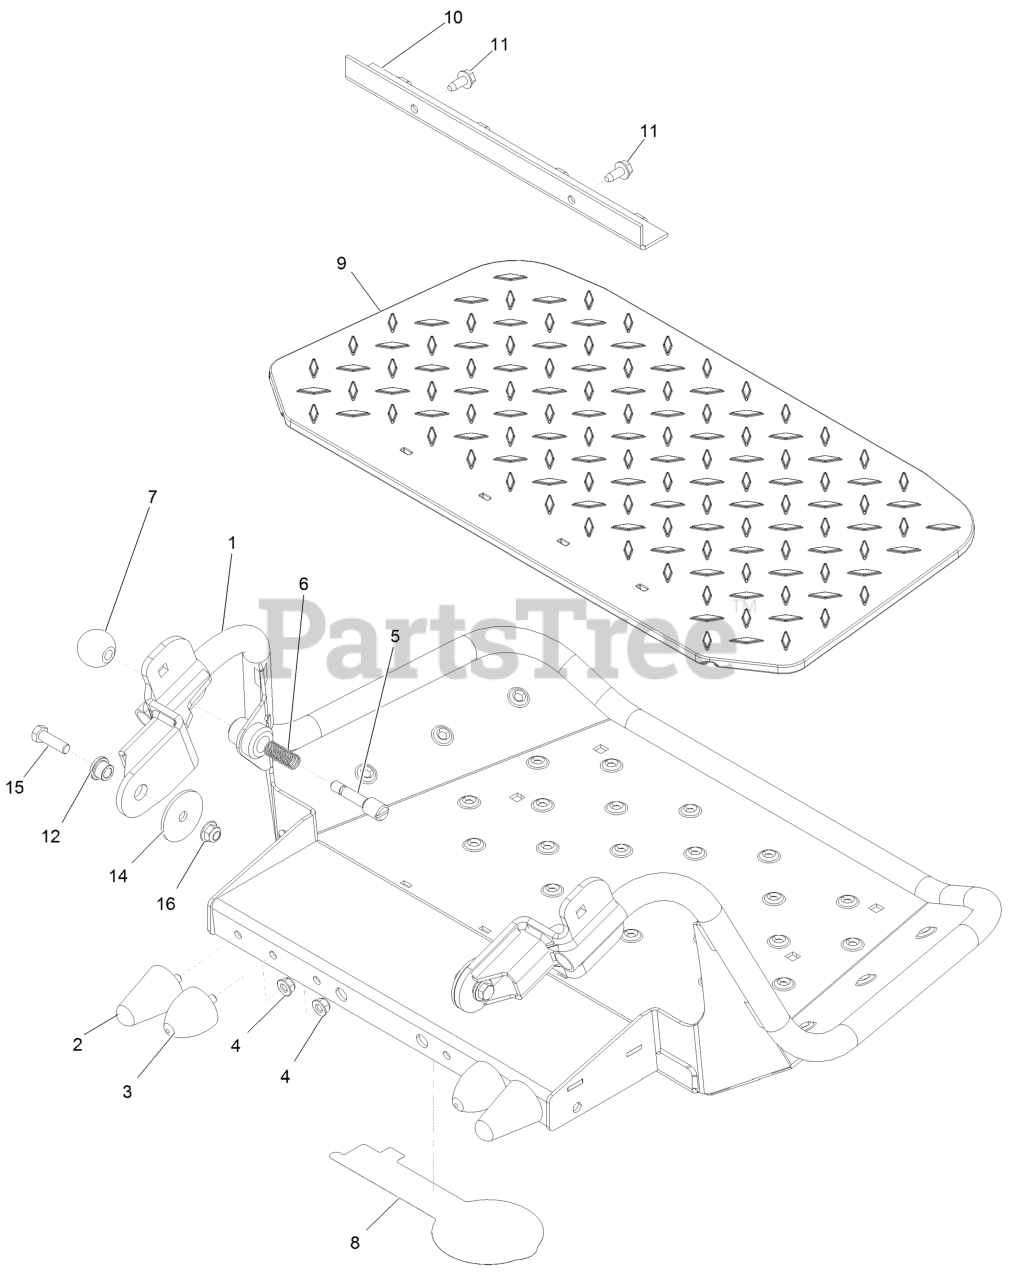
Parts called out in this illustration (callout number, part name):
1	PLATFORM ASM
2	BUMPER-RUBBER
3	BUMPER-RUBBER
4	NUT-HF, NI
5	PIN-LATCH
7	KNOB-BALL
8	DECAL-EXMARK LOGO
9	MAT-PLATFORM
10	CLAMP-SHIELD
11	Screw-HWH 5/16-18 X 3/4 Tf
12	BUSHING-FLANGED
14	WASHER-FLAT
15	SCREW-HH
16	NUT-HF, NI
